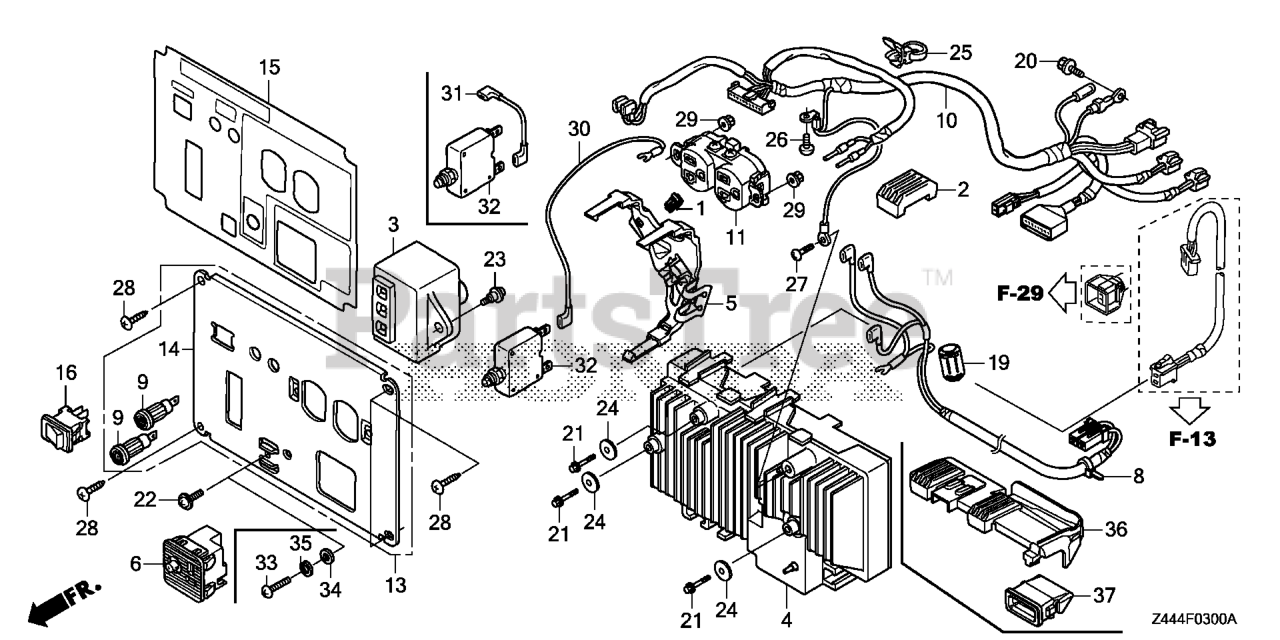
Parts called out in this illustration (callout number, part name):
1	CLIP, TUBE
3	SPARK UNIT
4	INVERTER UNIT
5	BRACKET, INVERTER HARNESS
6	RECEPTACLE, D.C.
8	SUB-WIRE HARNESS ASSY.
9	SOCKET, COMPOSITE
10	WIRE HARNESS ASSY., CONTROL
11	RECEPTACLE ASSY. (125V-20A) (MATSUSHITA)
13	PANEL, CONTROL
14	PANEL, CONTROL
15	MARK, CONTROL PANEL
16	SWITCH, AUTO-THROTTLE (OTAX)
20	BOLT, FLANGE (5X10)
21	BOLT, FLANGE (5X12)
22	SCREW, PAN (5X12) (GROUND CABLE)
23	SCREW, PAN (5X13)
24	WASHER, PLAIN (20MM)
25	BAND (100MM) (BLACK)
26	SCREW, PAN (5X8)
27	SCREW, PAN (5X10)
28	SCREW, TAPPING (5X16) (PO)
29	NUT, FLANGE (4MM)
30	WIRE, TERMINAL
32	PROTECTOR, CIRCUIT (20A) (WHITE)(TYCO)
32	PROTECTOR, CIRCUIT (20A) (BLACK)(JOEMEX)
36	RUBBER B, TANK MOUNTING
37	COVER, CONNECTOR
